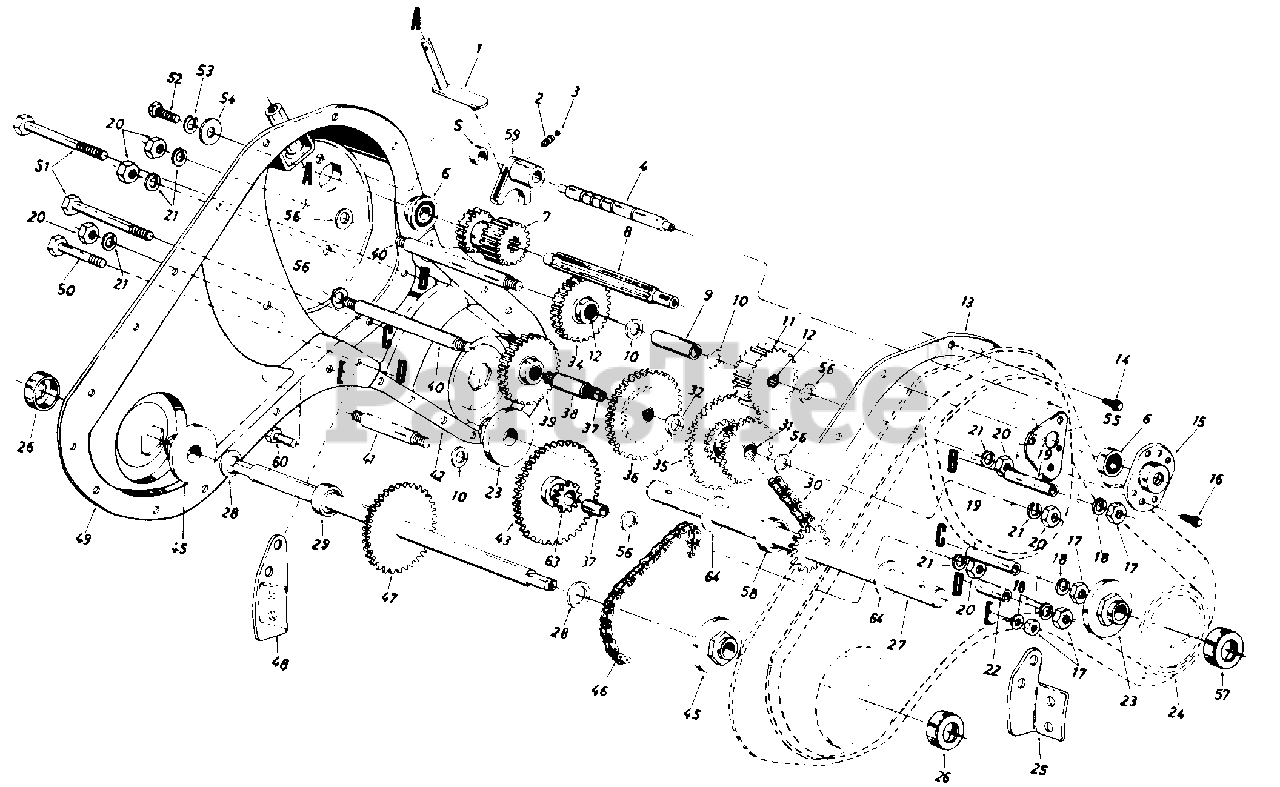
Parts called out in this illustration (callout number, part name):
1	Shifting Bracket Ass'y.
2	Compression Spring .50" Lg.
3	Ball Detent .250" Dia.
4	Detent Shaft 1/2" Dia.
5	Spacer.505" I.D. x .88" O.D.
6	Ball Brg. .62" I.D. x 1.38"
7	Spur Gear 16T
8	Input Spline Shaft 7/8"
9	Spacer .657" I.D. x 2.85" Lg.
10	Fl-Wash. .640" I.D. x 1.24"
11	Spur Gear 30T 7/8" I.D.
12	Needle Bearing 5/8" I.D.
13	Gasket Trans. Hsg.
14	Hex Wash. S-Tap Scr. 1/4-20 x.50" Lg.
15	1-3/8" Dia. Bearing Housing
16	Hex TT-Tap Scr. 1/4-20 x .75"
17	Hex Nut 5/16-18 Thd.
18	L-Wash. 5/16" I.D.
19	Spacer 1.56" Lg.
20	Hex Nut 7/16-20 Thd.
21	Bell-Wash. .45" I.D. x 1.0"
22	Spacer 1.015" Lg.
23	Tine Shaft Brg. 1.002 x 2.50
24	Trans. Housing Ass'y. L.H.
27	Tine Shaft Ass'y. 1" O.D.
28	Fl-Wash. .75" I.D. x 1.5" O.D.
29	Spacer .75" I.D. x .50" Lg.
30	Chain #50 5/8 Pitch x 52 Links Endless
31	Needle Bearing 5/8" I.D.
32	Fl-Wash. 5/8" I.D.
34	Spur Gear 30T 12/16" I.D.
35	30/44T Gear Ass'y. Comp.
36	Spur Gear 44T
37	Sleeve Bearing
38	Gear Hub 3/4" I.D. x 3" Lg.
39	Spur Gear 30T 1.0" I.D. x 1/2" W
40	Jack Shaft 5/8" Dia. x 5"
41	Jack Shaft 518" Dia. x 2.38"
45	Wheel Brg. .752" x 2.5"
46	#420 Chain 1/2 Pitch x 50 Links Endless
47	Wheel Shaft Ass'y. 15.6"
51	Hex Bolt 5/16-18 x 2.5"
52	Hex Bolt 1/4-20 x .62" Lg.
53	L-Wash. 3/8" I.D.
54	Fl-Wash. 1/4" I.D. x.93" O.D.
55	Gear Positioner Bracket
56	Fl-Wash. 7/16" I.D. x 1-3/8"
57	Dust Cover Ass'y. 1" Shaft
58	Spacer 1" I.D. x 2" O.D.
59	Shifting Fork
60	Hex Bolt 5/16-18 x .75" Lg.
63	1OT Sprocket Ass'y.
64	Thrust Wash. 1.03" I.D. x 1.62" O.D.
